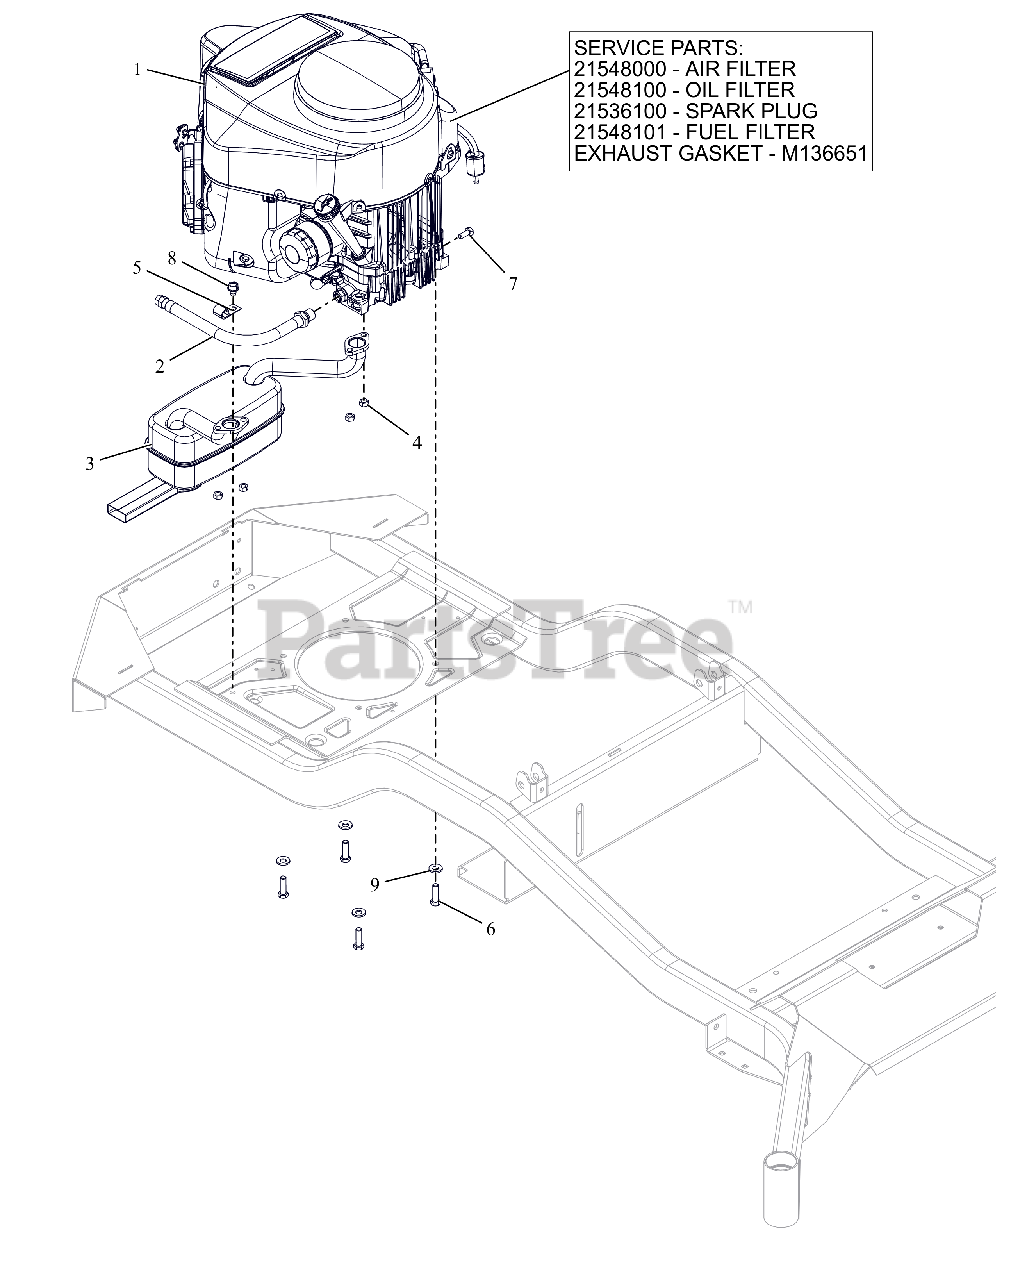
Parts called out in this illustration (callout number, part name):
1	ENGINE, KAWASAKI FR730 24HP
1	AIR FILTER, KAWASAKI FR
1	OIL FILTER, KAWASAKI FR
1	PLUG, SPARK
1	FUEL FILTER-KAWASAKI FR
1	GASKET, MUFFLER #
2	HOSE, OIL DRAIN
3	MUFFLER, KAWASAKI
4	NUT-LK-TOP M8-1.25 YWZC
5	J-CLAMP
6	BLT-HEX.38-16X1.25 G5YZ NYTORQ
7	BLT, HEX M8-1.25X20 G8.8 ZCC
8	@SCR-TAP .38-16X.50 HWH TR YWZ
9	WASHER, 3/8" SPRING DISC
